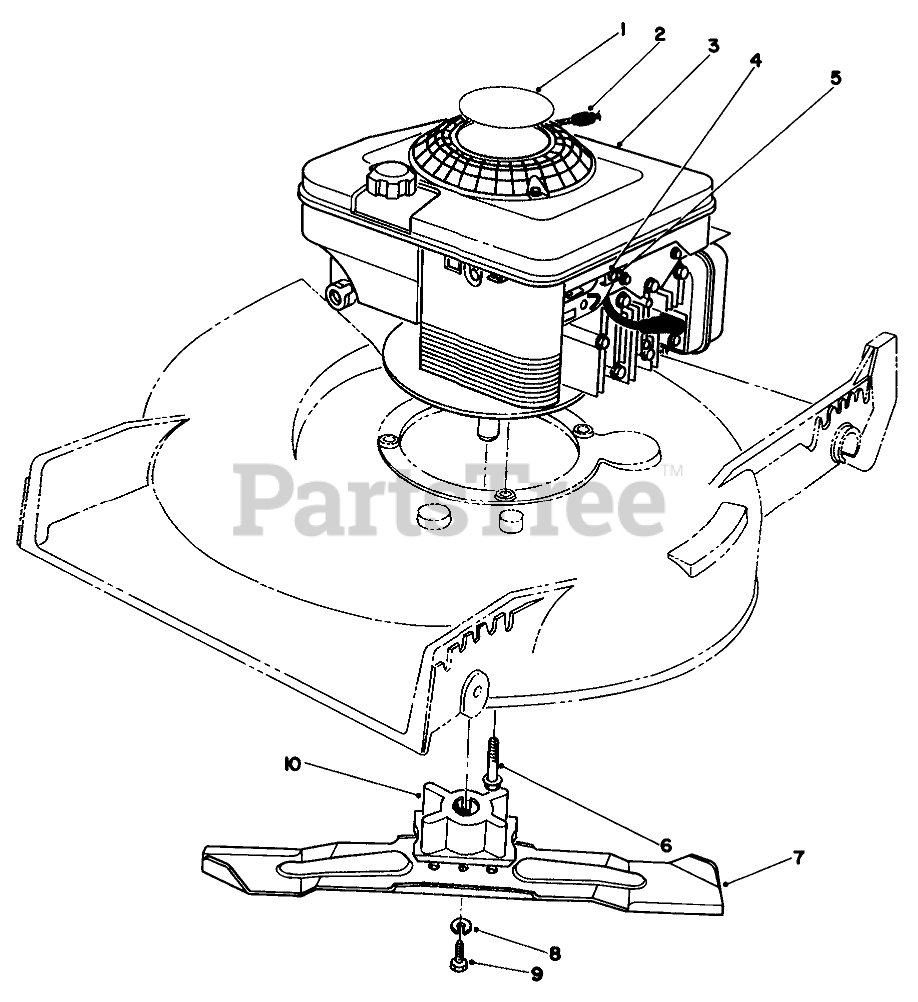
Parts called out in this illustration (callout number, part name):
1	DECAL - RECOIL
2	STOP-ROPE
4	CLAMP-CASING
5	Screw
6	SCREW-HWH
7	BLADE-21in
8	WASHER-LOCK
9	SCREW-BLADE
10	BLADE RETAINER
